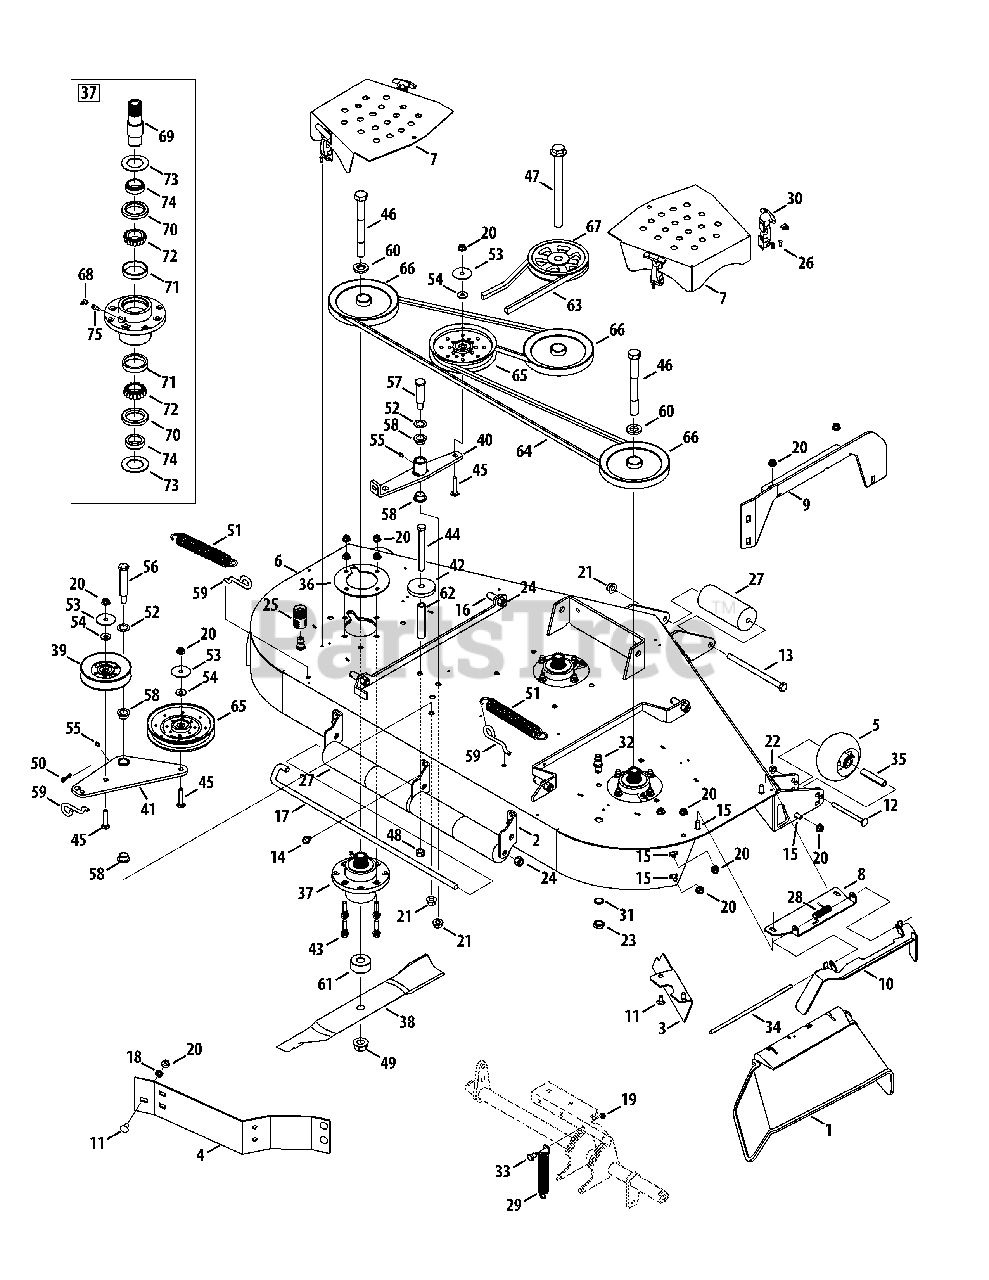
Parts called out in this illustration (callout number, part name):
1	Chute Deflector
2	Roller Mount Bracket
4	Baffle, 60" Adjustment
5	Complete Wheel, 5.00 Dia.
6	60" Deck Assembly
7	Deck Belt Cover
8	Chute Deflector Bracket
9	Deck Support Plate
10	Chute Extension Bracket
11	Carriage Bolt, 3/8-16 x .750
12	Carriage Bolt, 3/8-16 x 4.00
13	Hex Cap SCrew, 1/2-13 x 7.50
14	Screw, 3/8-16 x .500
15	Carriage Bolt, 3/8-16 x 1.00
16	Pin, 1/2-13 x .625 x 1.2
17	J-Hook w/ Threaded Roller
18	Push Nut, 3/8
19	Nut, 1/4-20, Flangelock
20	Nut, 3/8-16, Flangelock
21	Nut, 1/2-13, Flangelock
22	Nut, 3/8-16, Flangelock
23	Hex Nut, M16-1.5
24	Nut, 1/2-13, Hexlock
25	Water Nozzle Adaptor
26	Pop Rivet, 3/16
27	Front Roller
28	Torsion Spring, 0.639 x 2.16
29	Extension Spring, .969 x 6.180
30	T-Handle Latch Draw
31	Lock Washer, 17 x 23.8 x 1.95
32	Deck Water Nozzle
33	Shoulder Bolt, .437 x .50, 1/4-20
34	Chute Deflector Rod
35	Wheel Spacer
36	Spindle Support Plate
37	Spindle Assembly
38	Hi-Lift Blade, 21.0
39	Idler Pulley
40	Deck Idler Arm
41	Idler Assembly
42	Spacer, .5375 x 2.75 x .375
43	Carriage Bolt, 3/8-16 x 1.5
44	Hex Cap Screw, 1/2-13 x 5.00
45	Carriage Bolt, 3/8-16 x 2.00
46	Hex Cap Screw, 3/4-16 x 7.00
47	Hex Cap Screw, 3/4-16 x 9.00
48	Nut, 1/2-13, Hexlock
49	Nut, 3/4-16, Flangelock
50	Bow Tie Cotter Pin
51	Extension Spring, 1.248 x 8.5
52	Washer, .793 x 1.24 x .06
53	Washer, .406 x 1.92 x .060
54	Washer, .406 x 1.00 x .105
55	Grease Fitting
56	Shoulder Bolt, .75 x 3.25, 1/2-13
57	Shoulder Bolt, .750 x 2.23, 1/2-13
58	Flange Bearing, .75 x .52
59	Spring Rod Hook
60	Spacer, .812 x .218
61	Spacer, .760 x 2.00 x .925
62	Spacer, .405 x .75 x 3.875
65	Idler Pulley
66	Spindle Pulley
67	Drive Pulley
68	Grease Fitting, 1/4-28, 45 degree
69	Shaft, Blade Spindle
70	Seal, Oil
71	Bearing, Cup
72	Bearing, Cone
73	Washer, 1.05 x 2.52 x .076
74	Ring, Seal
75	Straight Adapter Fitting
